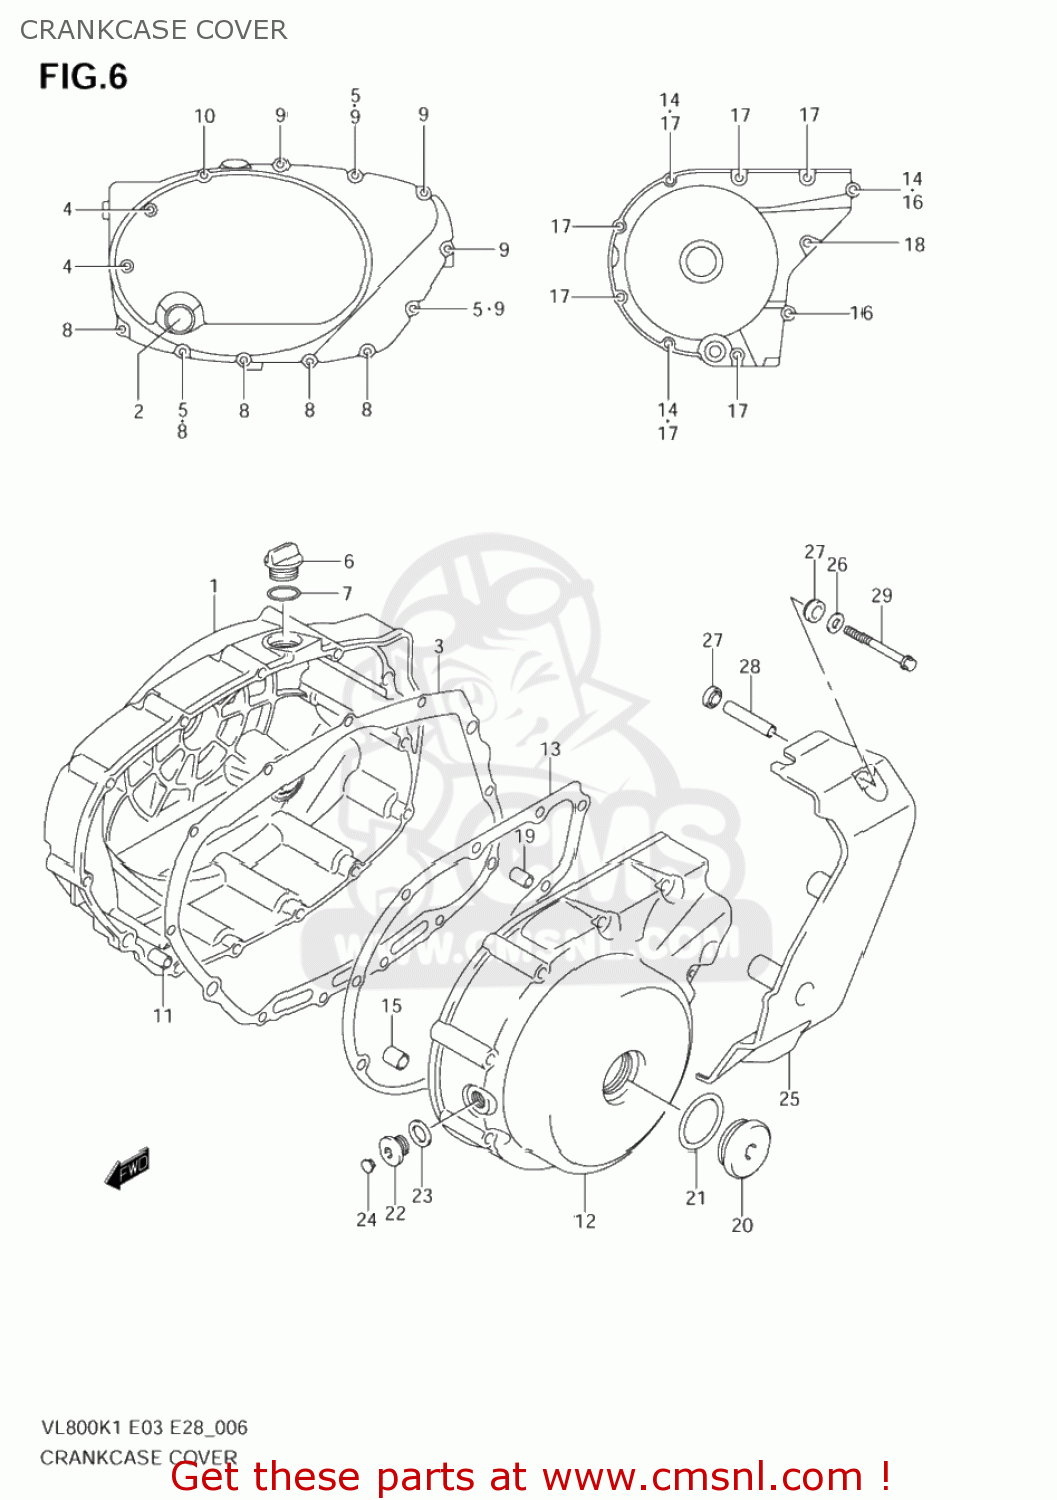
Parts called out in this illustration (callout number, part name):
1	COVER,CLUTCH
2	LENS,OIL LEVEL CHECK
3	GASKET,CLUTCH COVER (NAS)
4	BOLT(6X105)
5	GASKET(5.8X13X1.2) (NAS)
6	PLUG(20X10)
7	O RING(D:3.1,ID:16.8)
8	BOLT
9	BOLT
10	BOLT
11	PIN
12	COVER GENERATO
13	GASKET,GENERATOR COVER (NAS)
14	GASKET(5.8X13X1.2) (NAS)
15	PIN(8.4X11X20)
16	BOLT
17	BOLT
18	BOLT
19	PIN
20	Chrome Crankshaft Plug
21	O RING(D:3.1,ID:32.7)
22	PLUG,14X12
23	GASKET(13.8X18.8X4.8) (NAS)
24	CAP(OD:12)
25	COVER,SECONDARY DRIVE UNIT
26	WASHER(6.5X14X1.6)
27	WASHER(8.7X16X5)
28	SPACER(6.5X9X41.3)
29	BOLT
